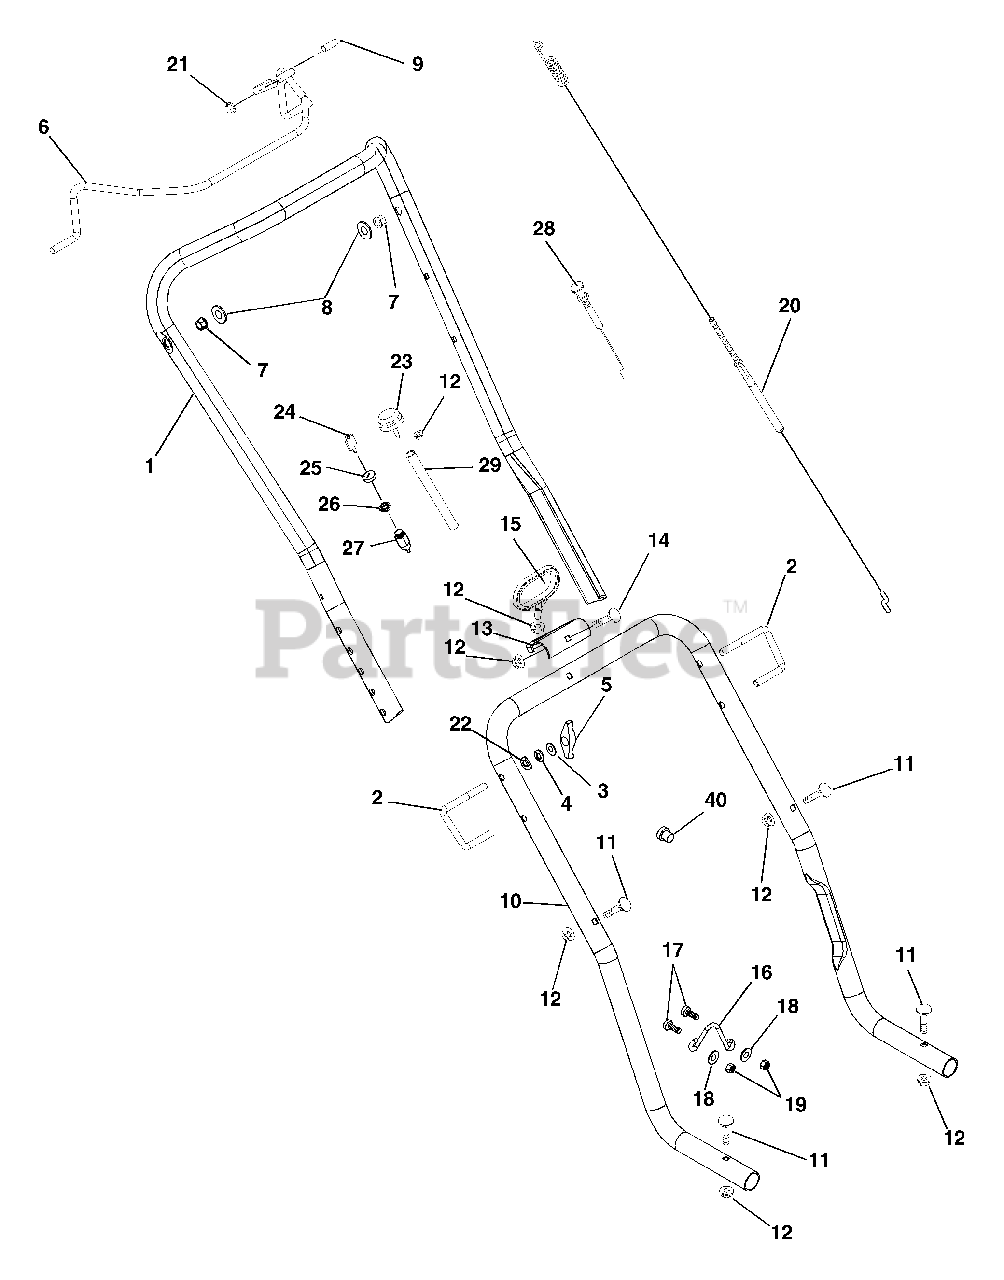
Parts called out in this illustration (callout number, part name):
1	HANDLEBAR, UPPER
2	J BOLT .31-18
3	WSHR-FL-STL .328X.875X.062YWZC
4	WSHR-LK .312X.097 HVY YWZC
5	KNOB - WING .312-18 UNC
6	BAIL SS LF
7	BSHG-FLG .325X.444X.440X.560
8	@WSHR-FL-STL.344X.688X.065YWZC
9	CAP, VINYL, .25 ID
10	HANDLEBAR, LOWER
11	BLT-RDHDSQNK .25-20X1.75 G5YZ
12	NUT-LK-FLG .250-20 PL BLK
13	BRKT-STARTER HANDLE
14	BLT-RDHDSQNK .25-20X1.50 PL BL
15	HANDLE, RECOIL START
16	GUIDE-ROPE
17	@SCR-MCH 10-24X.75 HWH YWZC
18	@WSHR-FL-STL.219X.50X.049 YWZC
19	@NUT-LK-NYL 10-24 W/INSRT YWZC
20	CABLE-CLUTCH CONTROL
21	PUSH NUT, .25
22	WASHER,SADDLE-.320 X.937 X.062
23	PRIMER ASSY
24	KEY -W/CAP
25	CAP - IGNITION SWITCH
26	NUT-PANEL .625-32 GRECO
27	SWITCH ASSEMBLY
28	CONTROL-CHOKE 5 HP
29	LINE-PRIMER
30	PLUG-HOLE .50 DIA
